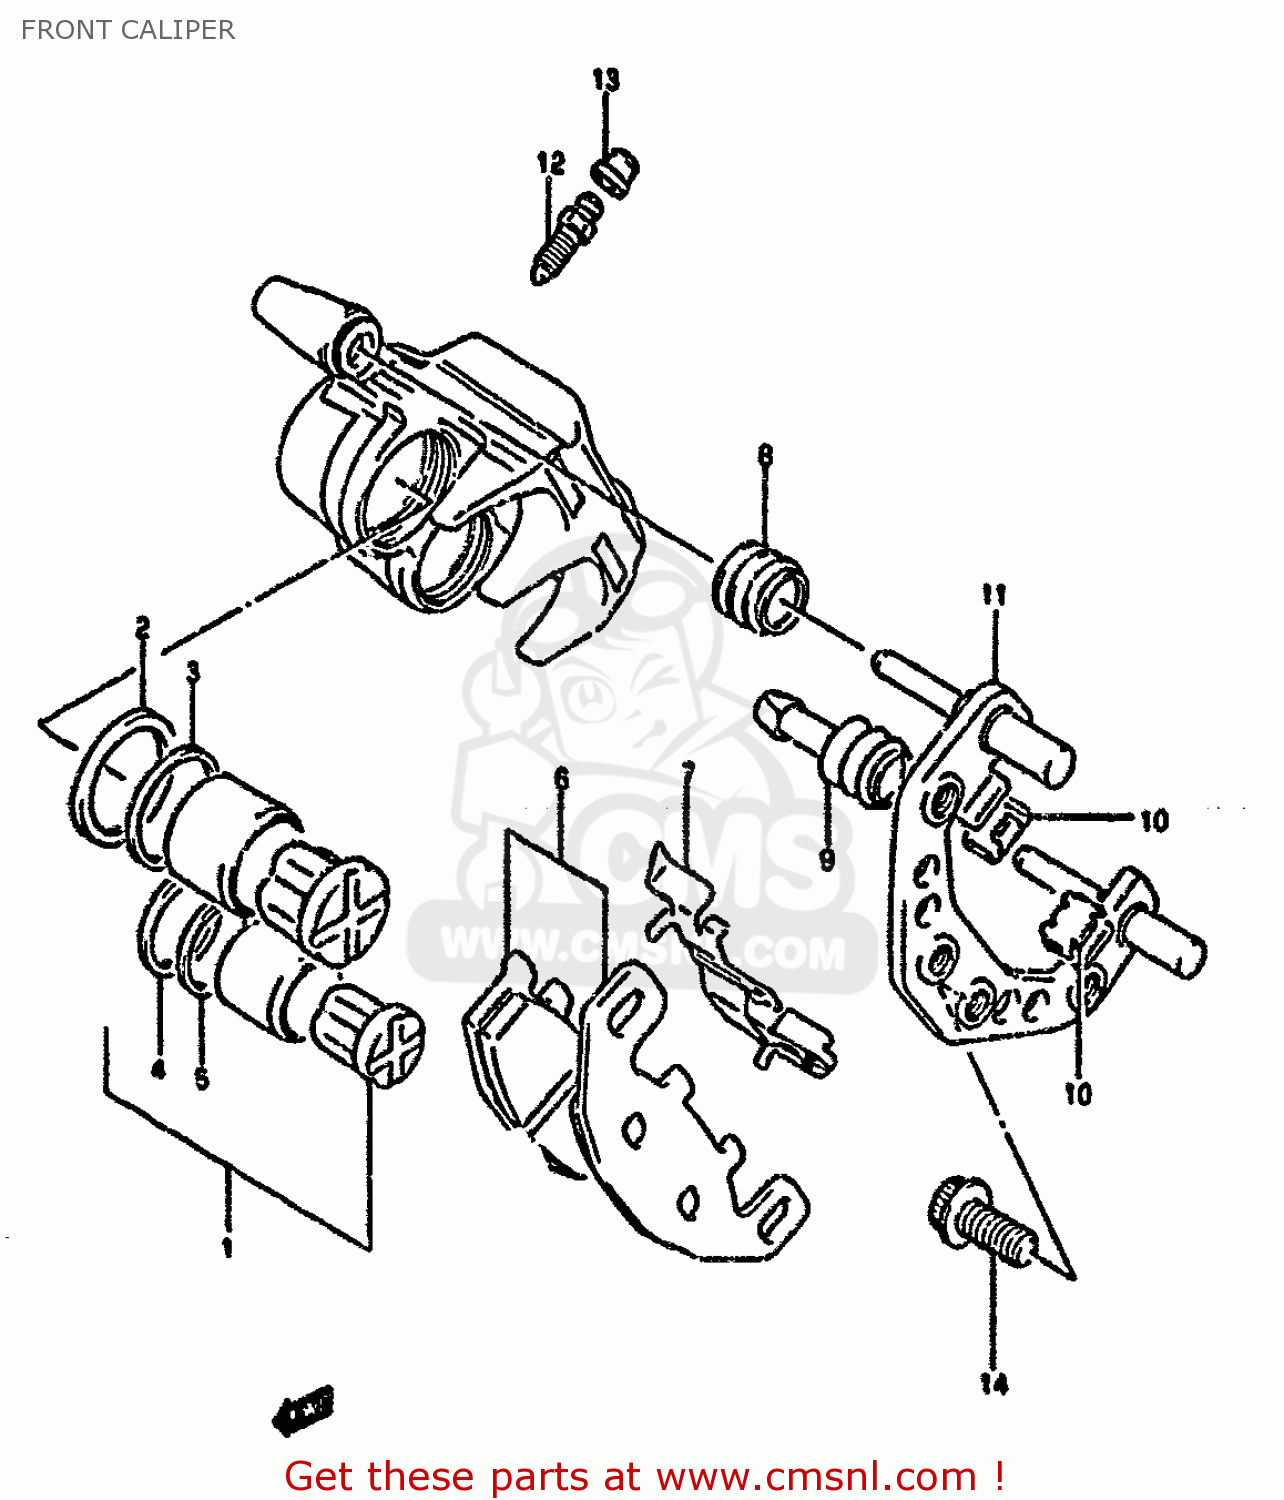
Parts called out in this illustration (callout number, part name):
1	PISTON SET
2	SEAL,PISTON
3	SEAL,WIPER
4	SEAL,PISTON
5	SEAL,WIPER
6	PAD SET (NAS)
7	SPRING,PAD
8	BOOT,AXLE
9	INSULATOR,AXLE
10	GUIDE,PAD
11	CARRIER,CALIPER
12	BLEEDER
13	CAP,BREATHER
14	BOLT
